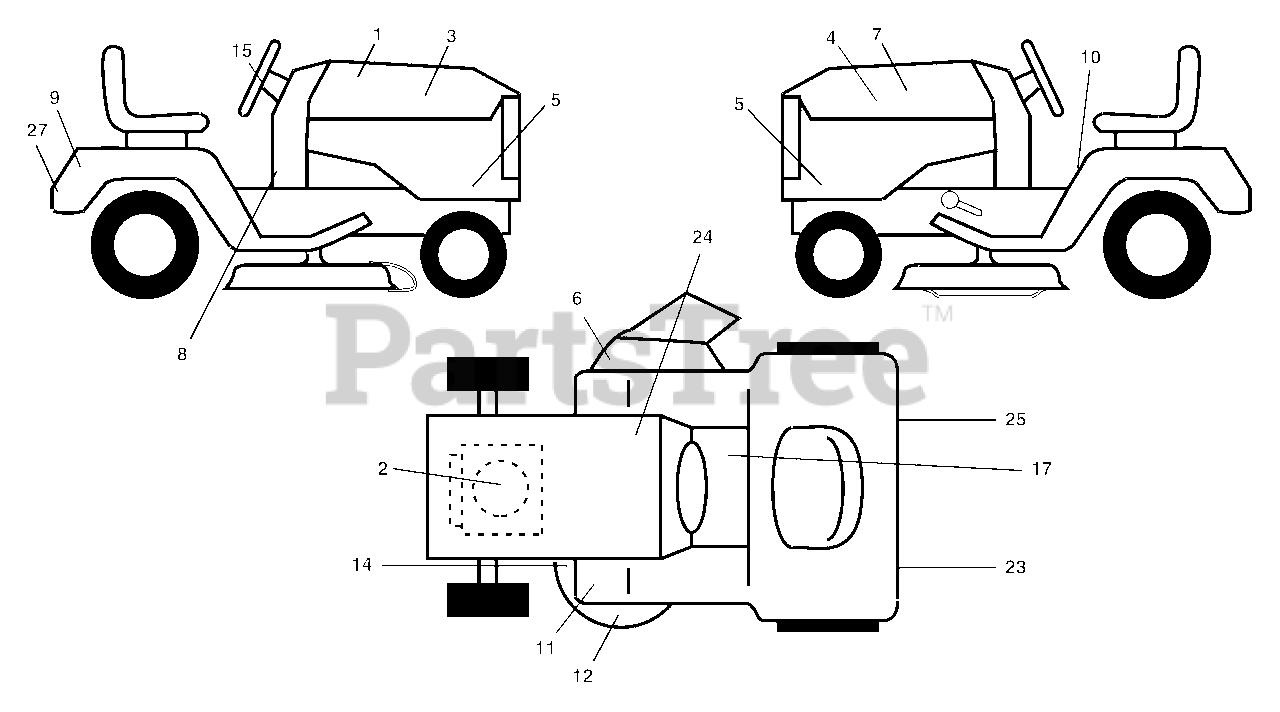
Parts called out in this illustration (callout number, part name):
1	Decal, Final
2	Decal, Engine
3	Decal, Hood, RH
4	Decal, Hood, LH
5	Decal, Side Panel
6	Decal, Warning
7	Decal, Hood Cust. Resp.
8	Decal, Dash
9	Decal, Fender
10	Decal, Danger
11	Decal, Foot Rest
12	Decal, Deck Caution
14	Decal, V-Belt Schematic
15	Decal, Ins. Strg Whl
17	Decal, Saddle Brake Parking
23	Reflector, Taillight LH
24	Decal, Btry Dngr/Psn
25	Reflector, Taillight RH
27	Decal, Drawbar
